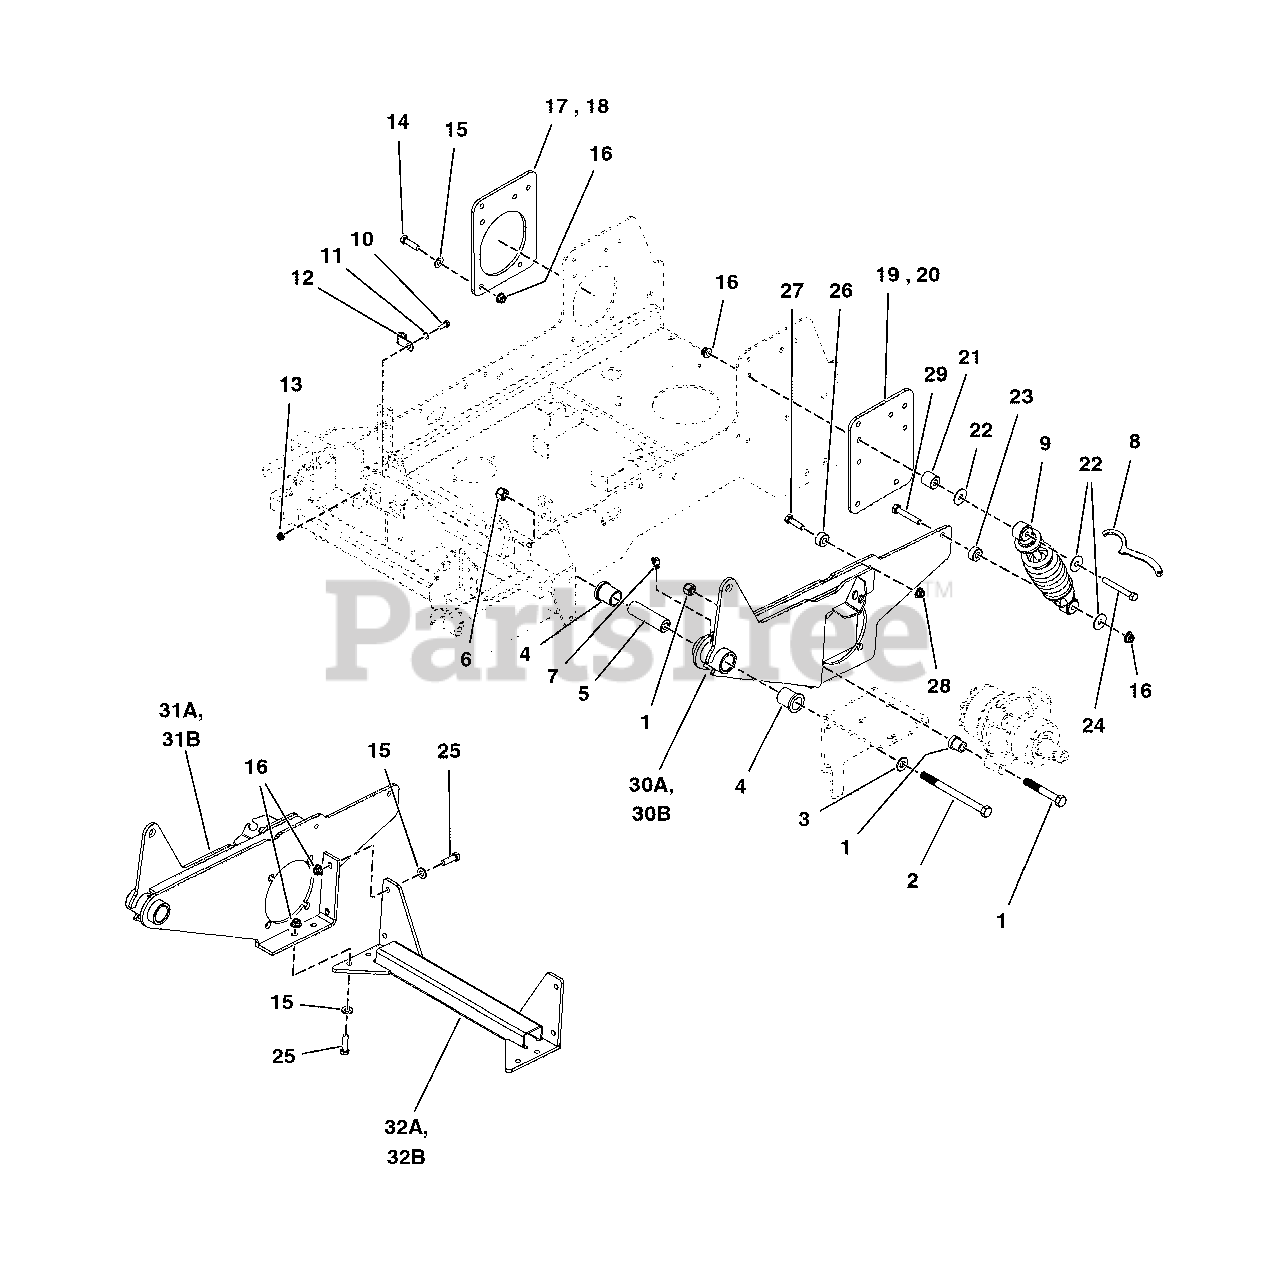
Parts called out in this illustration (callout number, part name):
1	See Hydraulic Components Replacement Group
2	BOLT, 1/2-13 X 6-1/2 GD8, YZ
3	WASHER, 1/2 SAE
4	BUSHING, FLANGE
5	SPACER, .52 X 1.00 X 3.42
6	NUT, 1/2-13 HEX NYLON LOCK
7	GREASE FITTING, 45 DEGREE
8	SPANNER WRENCH
9	SHOCK ASSEMBLY
10	BOLT 1/4-20 X 3/4"
11	WASHER, 1/4 SAE (5025154)
12	CLAMP, DOUBLE TUBE
13	NUT, 1/4-20 HEX NYLOCK FLANGE (5025391)
14	BOLT, 3/8-16 X 1-1/4 GD5
15	WASHER, 3/8 GD.9 FLAT
16	NUT, 3/8-16 Hex Nylock Flange
17	FRAME SUPPORT, RH
18	PLATE, FRAME SUPPORT, RH - RED
19	FRAME SUPPORT, LH
20	PLATE, FRAME SUPPORT, LH - RED
21	SPACER, .390 X 1.00 X 1.00 - YZ
22	WASHER-3/8 FENDER
23	SPACER, .39 X 1.00 X .50
24	BOLT, 3/8-16 X 3-1/2 GD5 CZ
25	BOLT, 3/8-16 X 1 GD5
26	SPACER, .34 X 1.54 X .25 UHMW
27	SCREW, 5/16-18 X 1, PHILLIPS HD, BZ
28	NUT, 5/16-18 HEX NYLOCK FLANGE
29	BOLT, 3/8-16 X 2-1/4 GD5 YZ
30A	WELD, MOTOR MOUNT - LH - RED
30B	WELD, MOTOR MOUNT - LH - RED
31A	WELD, MOTOR MOUNT - RH - RED
31B	WELD, MOTOR MOUNT - RH - RED
32A	KIT, TIE BAR (5404064A)
32B	KIT, TIE BAR (5404065A)
